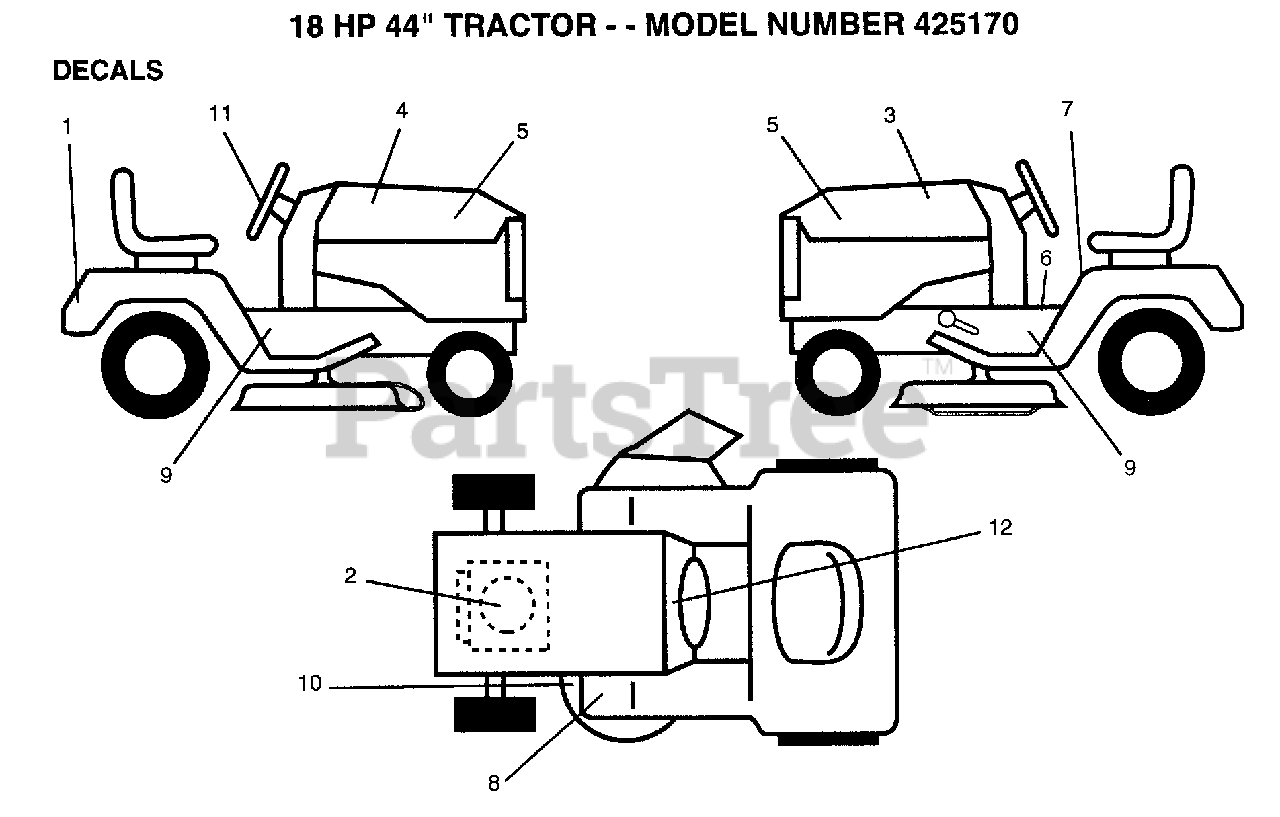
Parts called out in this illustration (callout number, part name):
1	DECAL.FENDER
2	DECAL.ENG.272559
3	DECAL.HD.LOWES.LH
4	DECAL.HD.LOWES.RH
6	DECAL BRAK PARK
7	DECAL
9	DECAL.CHASSIS
10	"DECAL.V.BELT.44"""
11	DECAL.WHL.STRG
12	DECAL.DASH.INST.
